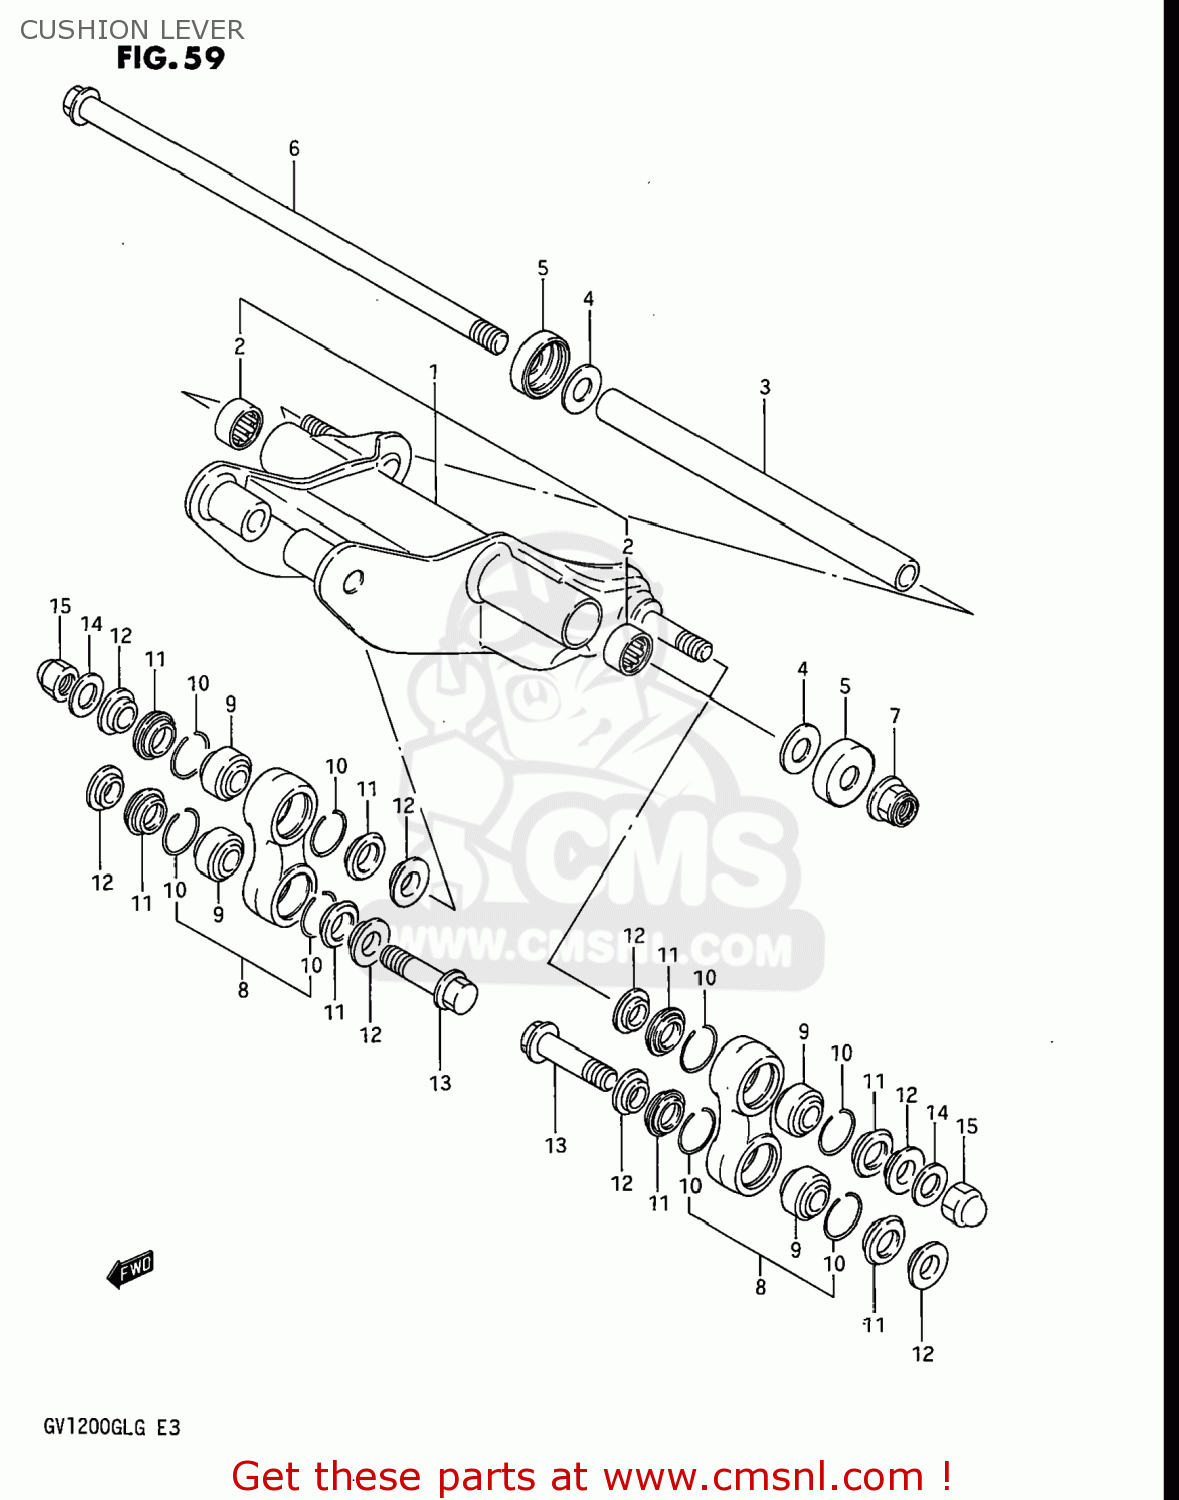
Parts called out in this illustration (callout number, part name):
1	LEVER SET,REAR CUSHION
2	ROLLER BEARING (17X24X25)
3	SPACER,REAR CUSHION LEVER
4	WASHER
5	COVER,RR SWGARM DUST SEAL
6	SHAFT,REAR CUSHION LEVER
7	NUT 12MM
8	LEVER SET,REAR CUSHION
9	BEARING(12X26X16)
10	RING,STOPPER
11	SEAL,RR CUSHION ROD DUST
12	SPACER,RR CUSHION ROD
13	BOLT,REAR CUSHION LEVER
14	WASHER
15	NUT
